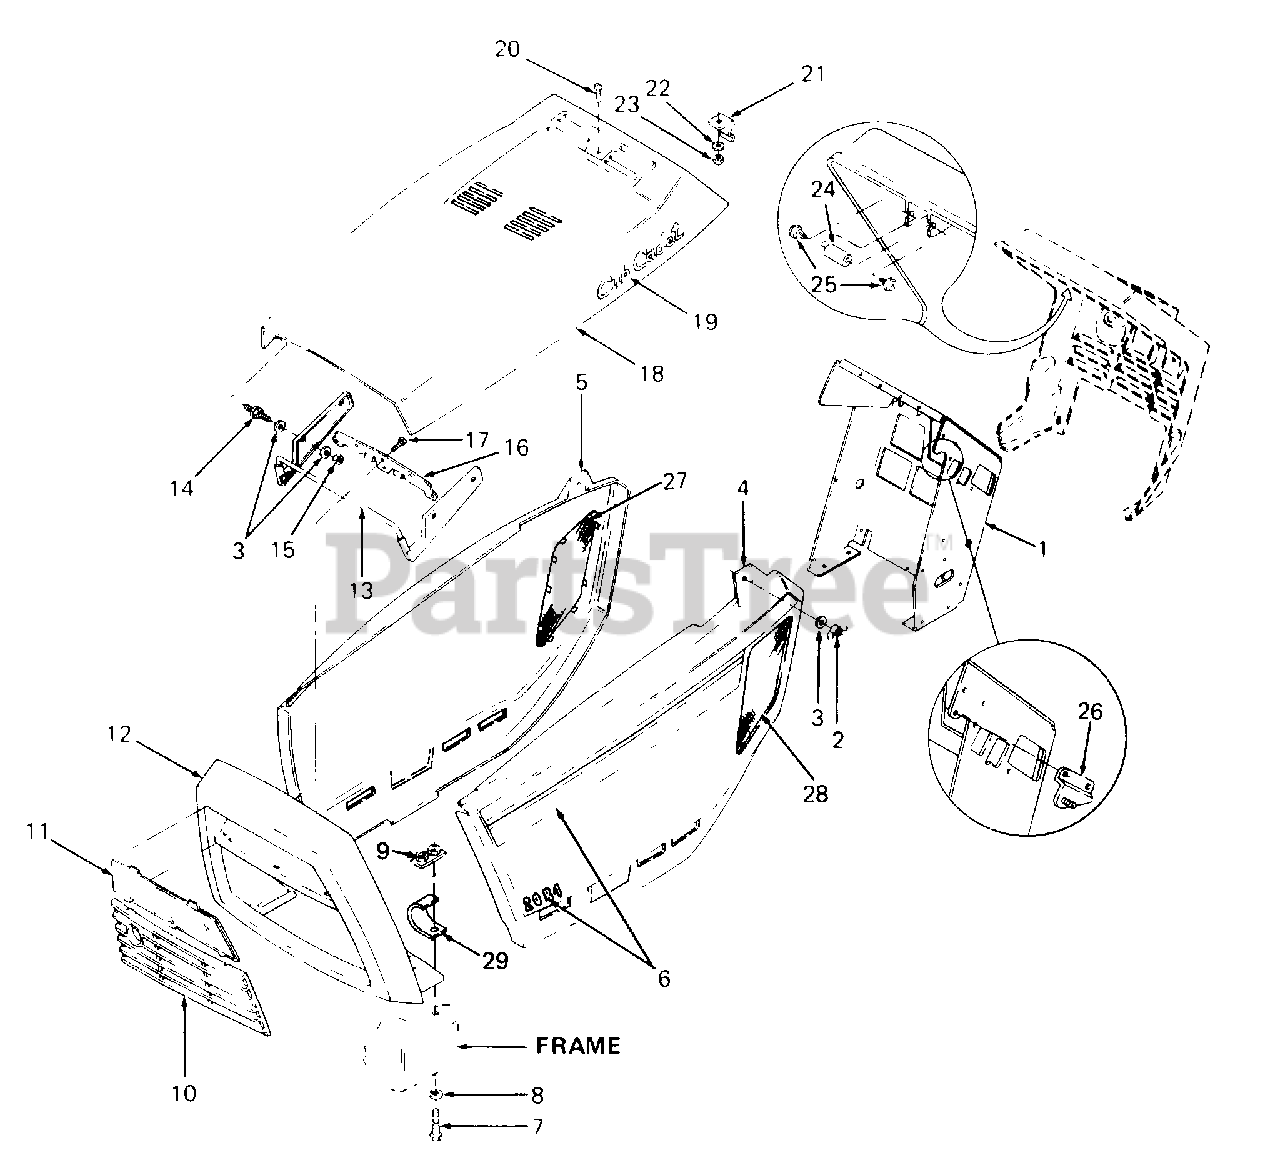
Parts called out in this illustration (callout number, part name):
3	Washer, Flat, .251 X .62 X .052 Thk
4	Panel, LH Side
5	Panel, RH Side
6	Graphics Kit, LH Side Panel
7	Screw, Hex Cap, 5/16-18 X 1.0 Lg GR5
8	Washer, Lock, 5/16
9	Retainer, Grille Housing
10	Grille, Insert
11	Grille, Lens
12	Grille w/Label
15	Nut, Hex Patch Lock, 1/4-20
18	Hood
19	Graphic, Cub Cadet Script w/Studs
20	Screw, Truss Hd, #8-32 X.38 Lg
21	Clip, Hood Latch
22	Washer, Flat, .16 X .38 X .045 Thk
23	Nut, Hex Keps, #8-32
24	Pin, Latch
25	Screw, Phillips Hd Truss Mach, 1/4-20 X.50 Lg
